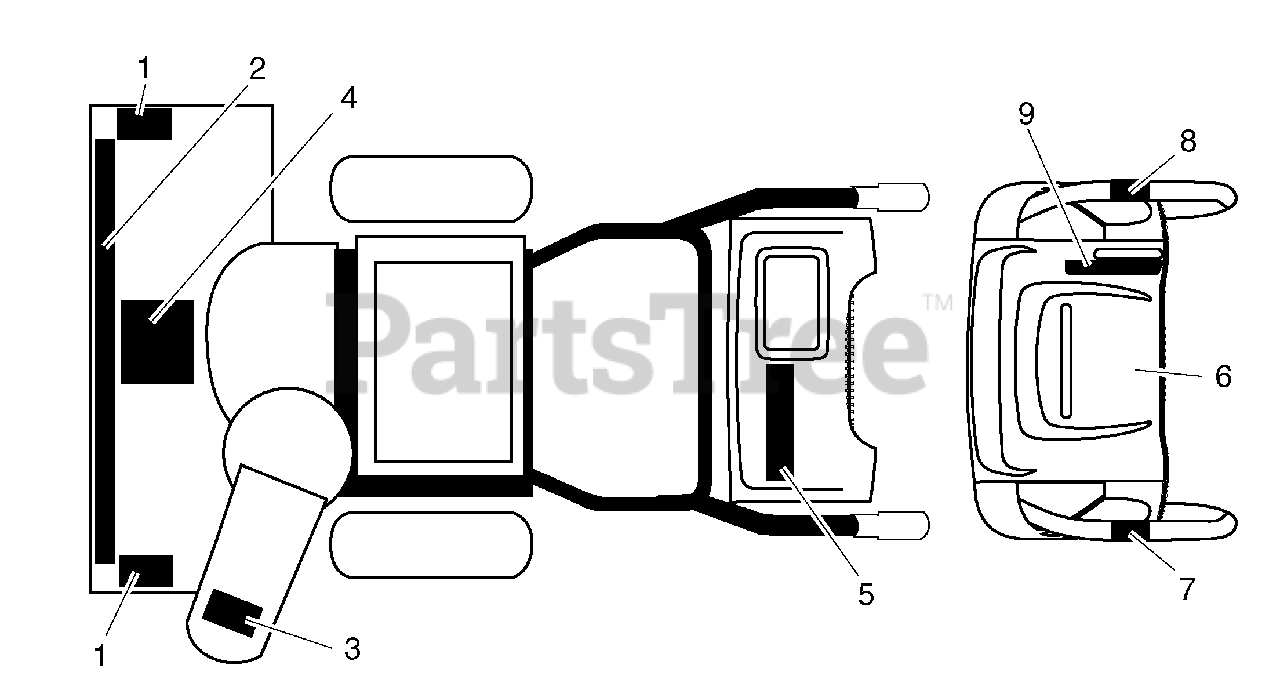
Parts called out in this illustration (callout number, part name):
1	DECAL, DANGER
2	DECAL, POULON PRO, 8.5 HP/27"
3	DECAL, DANGER, DEFLECTOR
4	DECAL, DANGER
5	DECAL, POULON PRO
6	DECAL, INSTRUCTION
7	DECAL, TRACTION LEVER
8	DECAL, AUGER LEVER
9	DECAL, SPEED CONTROL
9	OWNER'S MANUAL, ENGLISH
9	OWNER'S MANUAL, FRENCH
